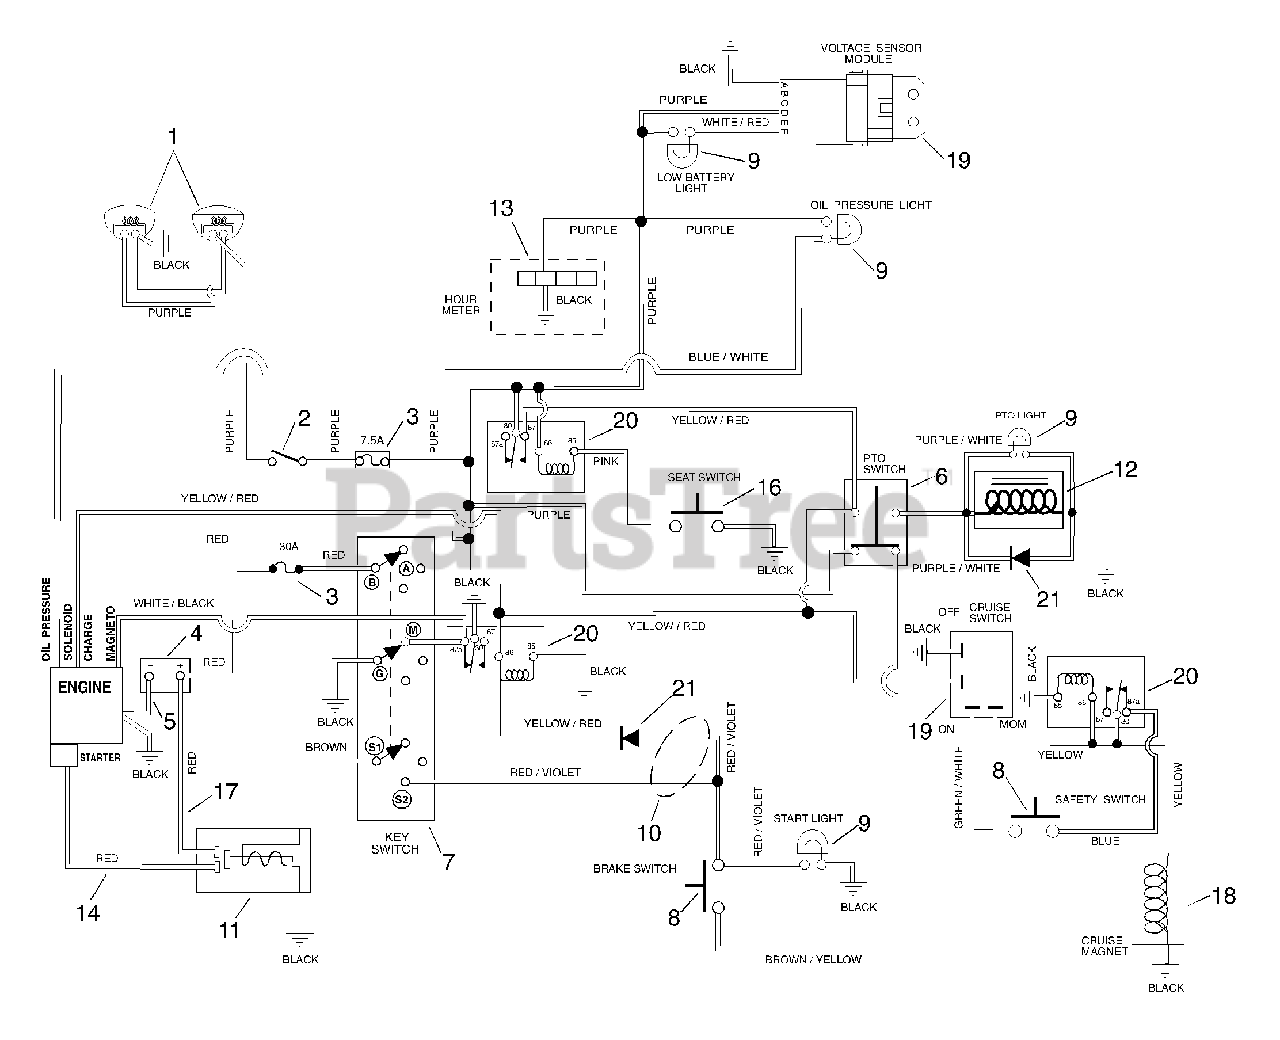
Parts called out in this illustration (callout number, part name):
1	HEADLIGHT- RH
1	HEADLIGHT- LH
2	SWITCH - LIGHT
3	7.5 AMP Fuse
3	30 AMP Fuse
4	BATTERY W/TUBE
5	GROUND CABLE .31X22.00X.31
6	PTO KNOB/ SWITCH ASSY
7	KEY SWITCH
8	SWITCH- SINGLE POLE N.O.
9	#194 Bulb
10	HARNESS, WIRING - 1640B&S TWIN
10	HARNESS, WIRING - 1648B&S TWIN
10	CLUTCH, ELECTRIC - WARNER
11	SOLENOID
12	ELECTRIC CLUTCH/BRAKE (3.4AMP)
13	HOURMETER KIT- SIERRA
14	START CABLE 22"
15	STARTER CABLE 6.75"
16	SWITCH- SEAT
17	SWITCH - CRUISE
19	MODULE - VOLTAGE SENSOR
20	RELAY
21	MOLDED DIODE PLUG 1 AMP
